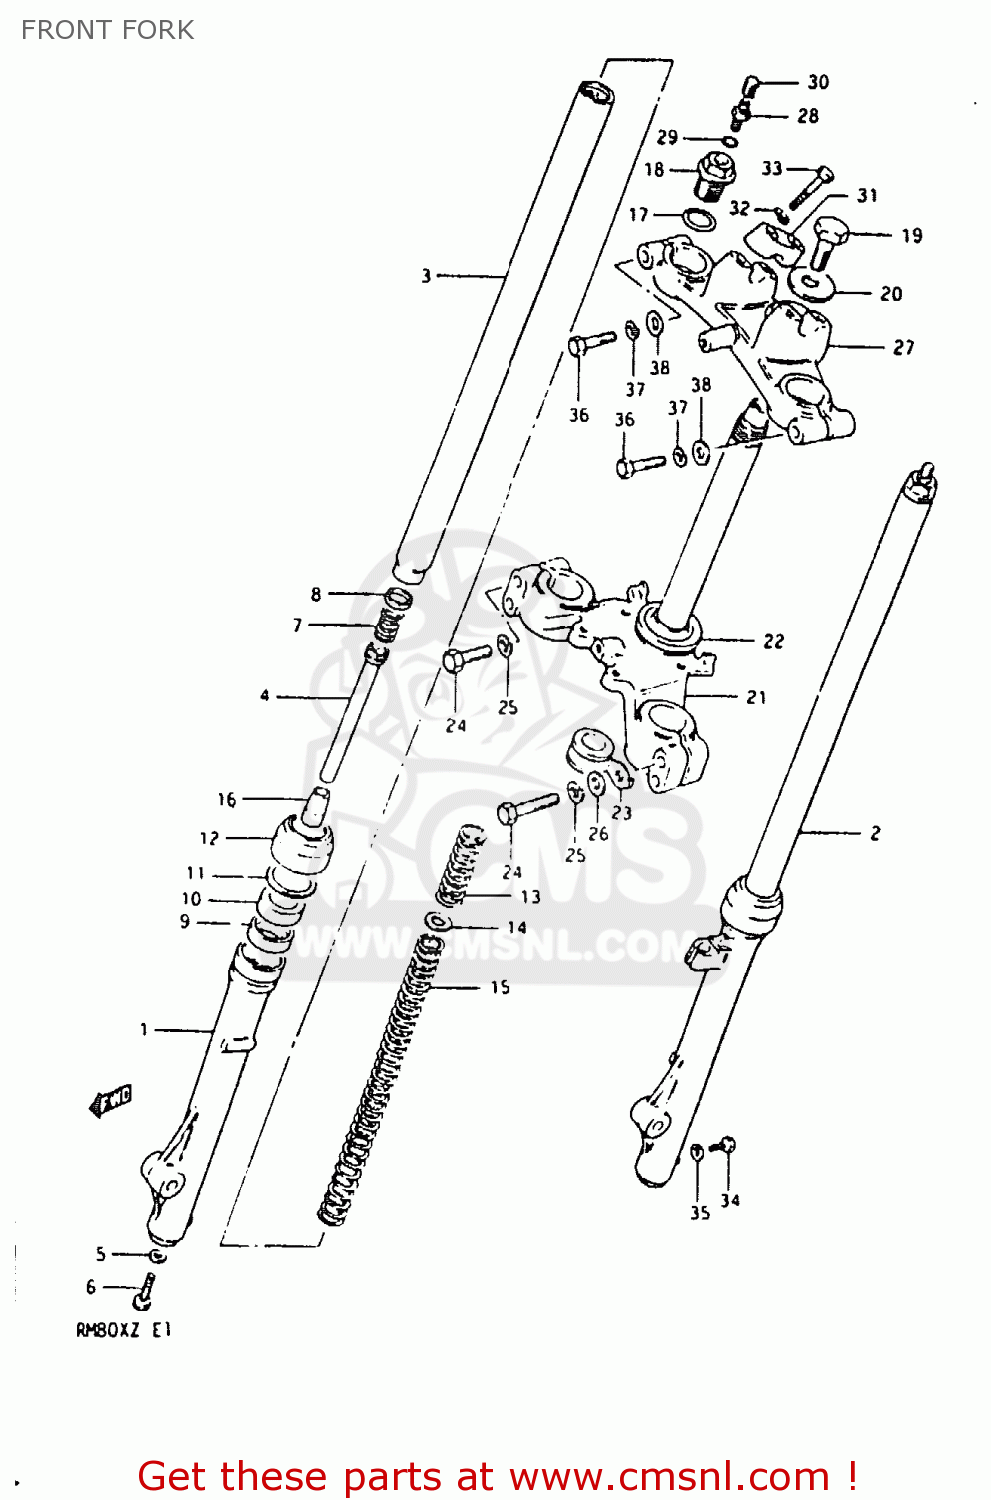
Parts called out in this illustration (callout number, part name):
1	TUBE,OUTER,RIGHT
2	TUBE,OUTER,LEFT
3	TUBE,FORK,INNER
4	CYLINDER,FRONT FORK
5	GASKET (NAS)
6	BOLT(8X27)
7	SPRING,REBOUND
8	RING,PISTON
9	SPACER,SEAL
10	SEAL,OIL
11	CIRCLIP,FORK OIL SEAL
12	SEAL,DUST
13	SPRING,FRONT FORK
14	SEAT,SPRING
15	SPRING,FRONT FORK
16	PIECE,OIL LOCK
17	O RING
18	BOLT,FORK INNER TUBE
19	BOLT,STEERING STEM HEAD
20	WASHER
21	STEM,STEERING
22	RACE,STEERING OUTER LWR
23	GUIDE,CABLE
24	BOLT,M10X1.25X
25	LOCK WASHER
26	WASHER
27	HEAD,STEERING STEM
28	VALVE,FRONT FORK AIR
29	O-RING
30	CAP
31	HOLDER,HANDLEBAR
32	LOCK WASHER
33	BOLT
34	BOLT
35	GASKET,DRAIN,PLUG (NAS)
36	BOLT 8X40
37	LOCK WASHER
38	WASHER
